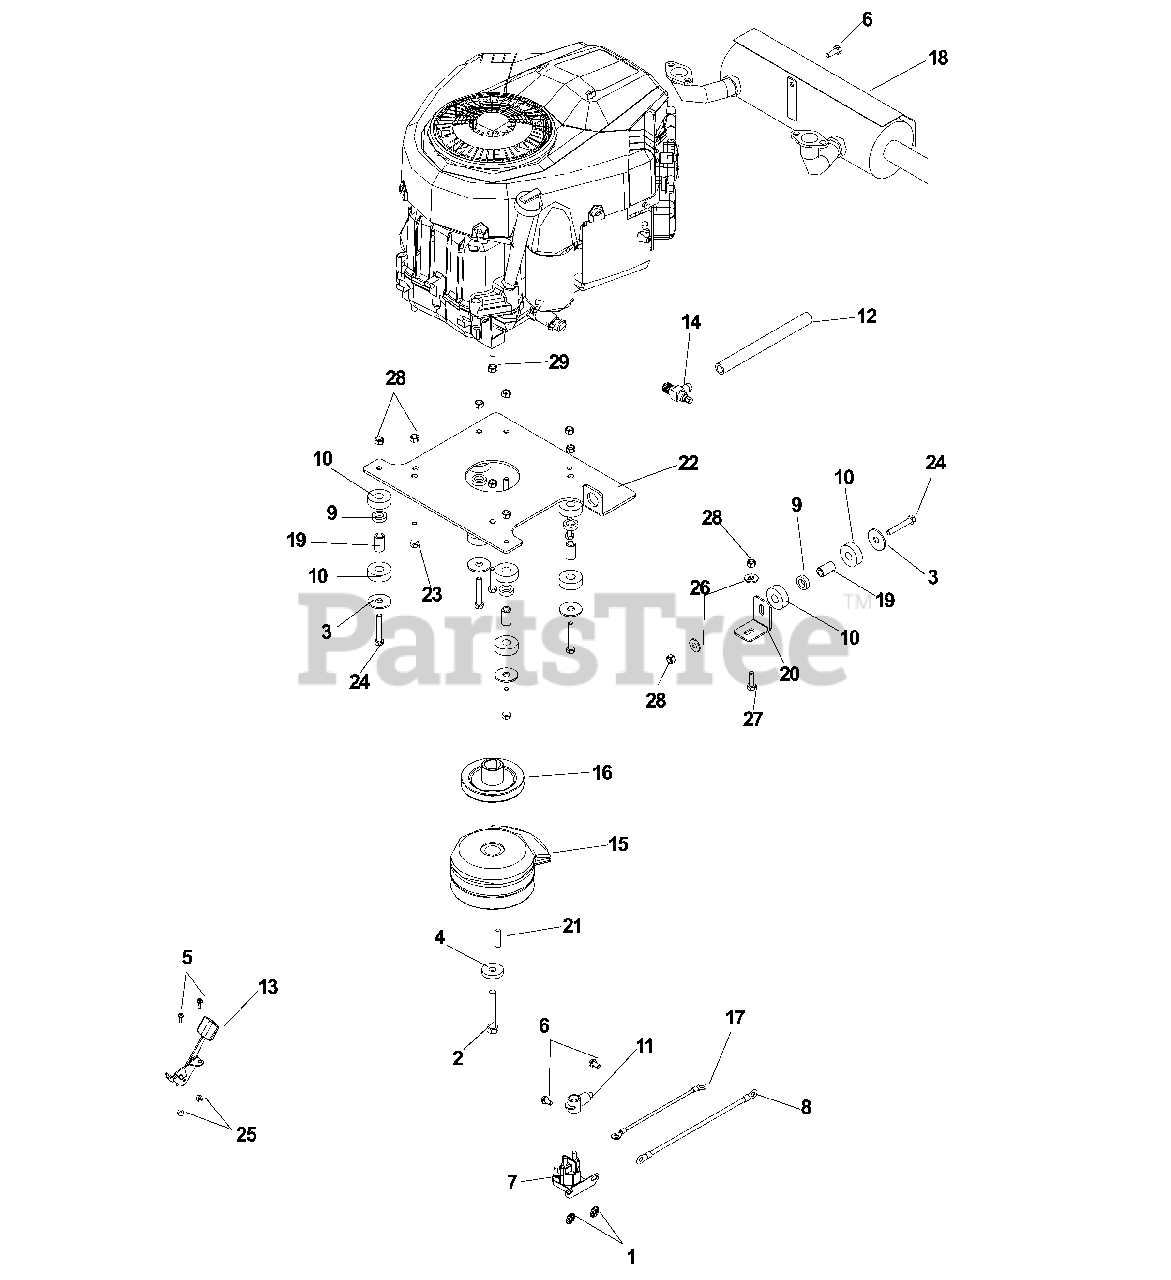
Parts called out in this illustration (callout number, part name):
1	WASHER 1/4 EXTLW STAR ZD
2	HCS 7/16-20 X 2-3/4
3	WASHER 7/16 FLAT ZD
4	WASHER .43X1.38X.25
5	SCREW #10-24 X 5/8
6	1/4-20 X 1/2 HWH FORM SCR H
7	SOLENOID
8	BATTERY GROUND CABLE
9	ISO-MOUNT INSERT
10	ISO-MOUNT BUSHING
11	TERMINAL COVER-SM
12	OIL DRAIN HOSE
13	CABLE THROTTLE
14	OIL DRAIN
15	ELEC. CLUTCH
16	ENGINE PULLEY
17	SOLENOID TO STARTER CABL
18	MUFFLER
19	ISO MT. BUSHING
20	ISO MT. BRKT.
21	KEY 1/4`SQ X 1-1/4`
22	ISO-MT SPDZTR
23	CAPSCREW 5/16 X 1/1/2 HEX HEAD
24	HCS 5/16-18X2
25	NUT 10-24 NYLOC
26	FLAT WASHER 5/16 SAE
27	HCS 5/16C X 1
28	NUT 5/16 NYLOC
29	NUT 1/4-20 JAM
